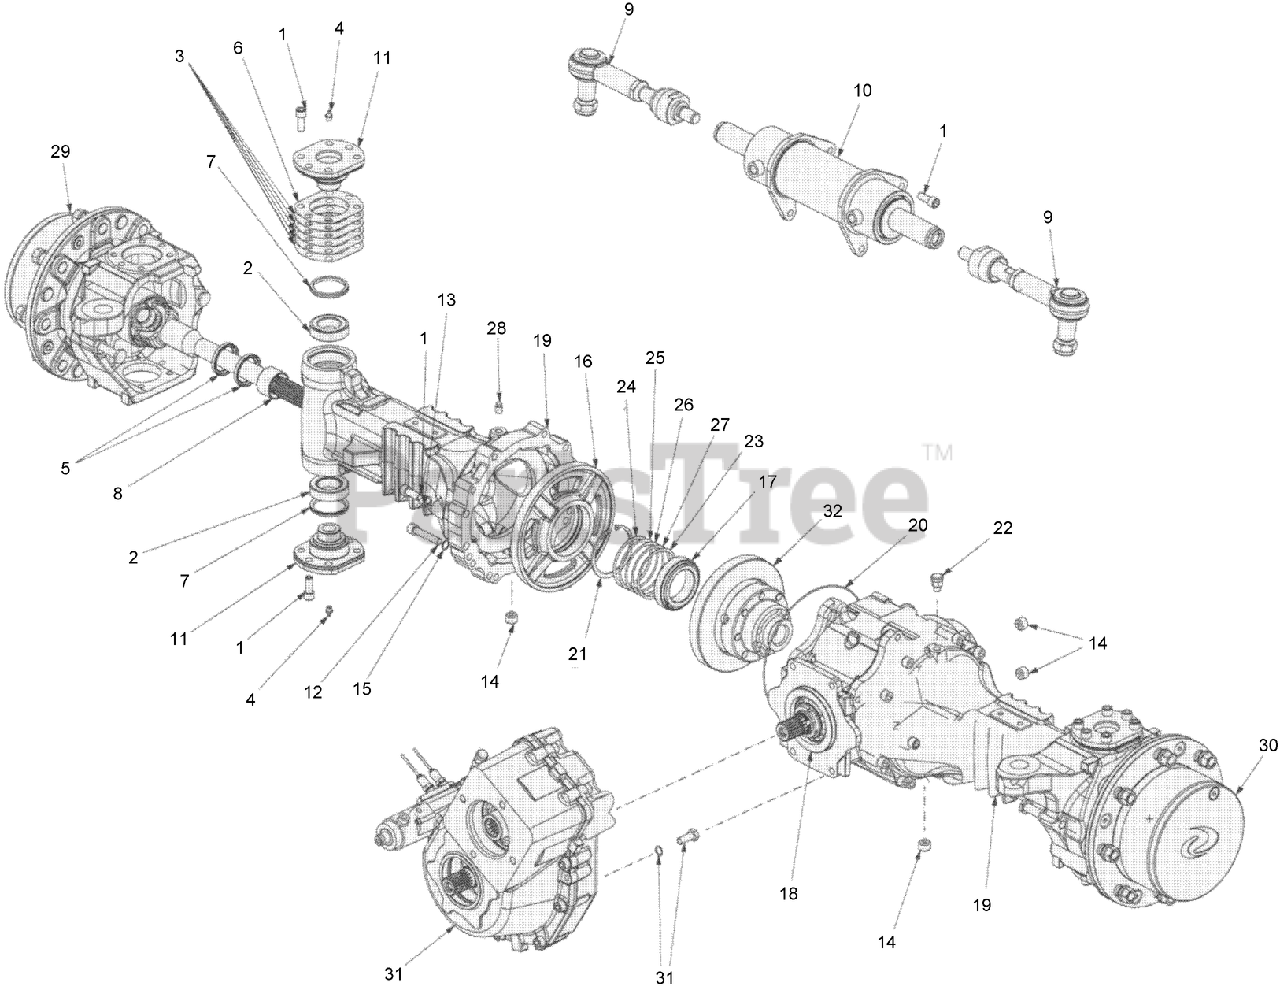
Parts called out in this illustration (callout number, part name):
2	JOINT-BALL
4	JOINT-Lube
7	V-RING
8	Bushing
9	Rod-Tie
10	Cylinder-Steering
11	PIN-Flagged
15	Washer
16	FLANGE-Differential
17	Bearing
19	HOUSING-Side
20	O-RING
21	RING-SNAP
22	PLUG-Oil Filter
29	GROUP-Wheel Hub
30	GROUP-Wheel Hub
31	GROUP-Gearbox
32	GROUP-Differential
